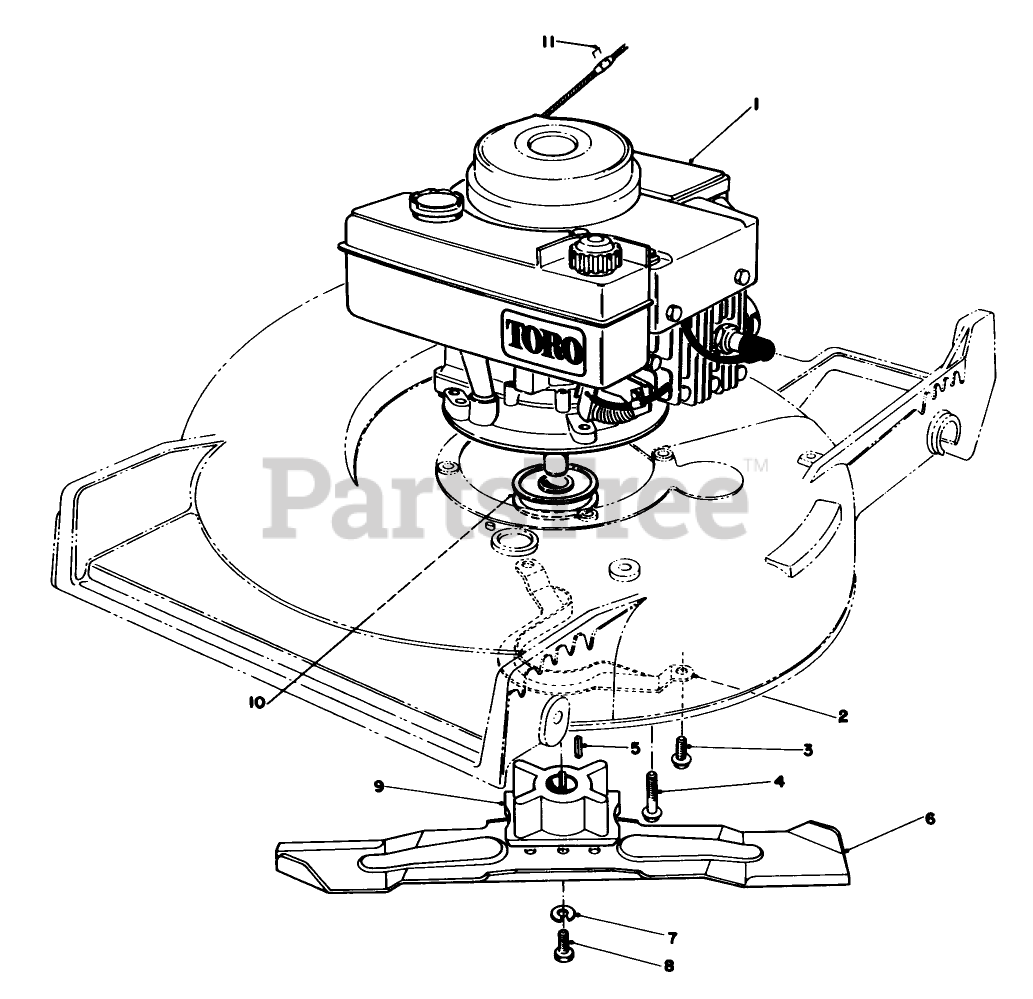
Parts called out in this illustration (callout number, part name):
2	BELT GUIDE
3	Screw
4	3/8-16 X 2 CAPSCREW
5	KEY-SQUARE
6	BLADE-21in
7	WASHER-LOCK
8	SCREW-BLADE
9	Retainer Blade
10	PULLEY-DRIVER
11	Staple
